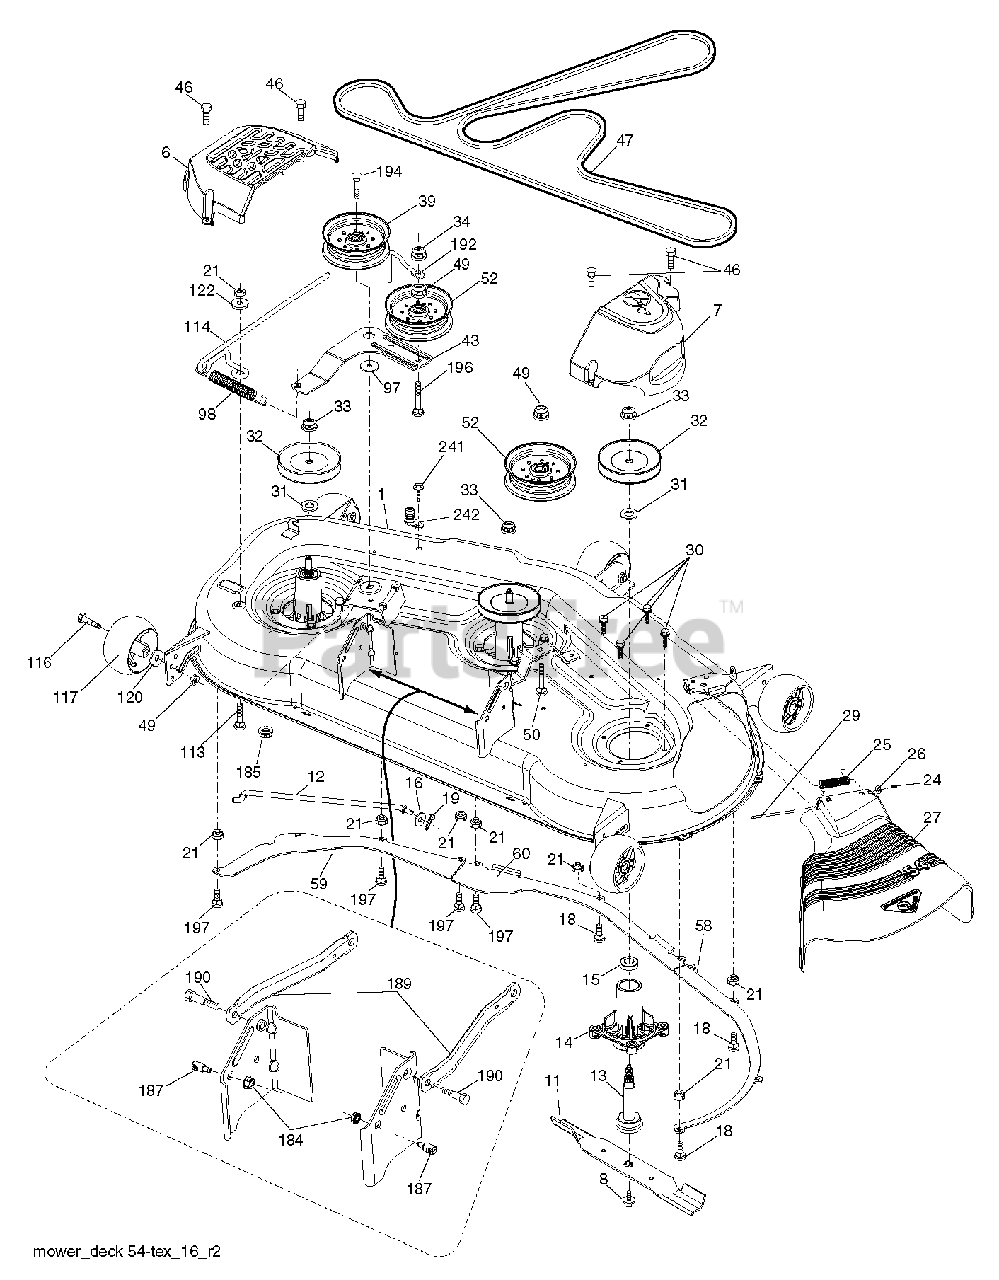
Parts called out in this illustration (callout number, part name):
1	DECK, COMPLETE, 54"E.HDHP.GWB.668
1	DECK, SHELL W/TUBES, 54".ORANGE
6	COVER.MANDREL.LH.54"20
7	COVER.MANDREL.RH.54.20
8	BOLT.WASHER.ASM.7/16-2
11	BLADE.BAGGING.54"
12	ROD.ANTI.SWAY.48/54"K4
13	SHAFT ASM MANDREL
14	HOUSING.MANDREL.4PT.
15	BEARING
16	WASHER
18	BOLT
19	PIN.COTTER.5/16.BOW TI
21	LOCKNUT
24	CAP-SLEEVE LT
25	SPRING, TORSION
26	NUT PUSH M
27	DEFLECTOR
29	ROD.HINGE
30	SCREW, WASHER HEAD
31	WASHER.SPACER.MANDREL
32	PULLEY/MANDREL
33	NUT.FLANGE.LOCK.TOP
34	LOCKNUT
39	RB PULLEY.IDLER.4.50/HUB SPEC
43	ARM.IDLER
46	SCREW.1/4-20X5/8
47	BELT.DRIVE.54."2006
49	NUT LOCK FLG 3/8-16 UNC
50	BOLT
52	PULLEY.IDLER.2006
58	BAFFLE.RIGHT.54"
59	BAFFLE.LEFT.54"
60	BAFFLE CENTER 54" MOWER
97	WASHER
98	SPRING, DECK DRIVE
113	BOLT CRT
114	ROD TENSION RELIEF
116	BOLT.SHOULDER.3/8-16X3-5/8.
117	WHEEL. GUAGE RALLY
120	WASHER
122	BUSHING.RELIEF.TENSION
184	NUT LOCK HEX FLANGE 5/16-18
185	NUT.LOCK.FLANGE.7/16
187	STUD.FASTNER.W/ANTI-ROTATE
189	ARM.SUSPENSION.MOWER
190	BOLT.SHOULDER
192	KEEPER.BELT.IDLER.54"T
194	BOLT.HEX.WASHER.HEAD.7/16-24X
196	BOLT
197	BOLT
241	SCREW.TT.#10-32X.5.3/8.FLANGE
242	PORT.WASHOUT
242	COUPLING.QUICK CONNECT
